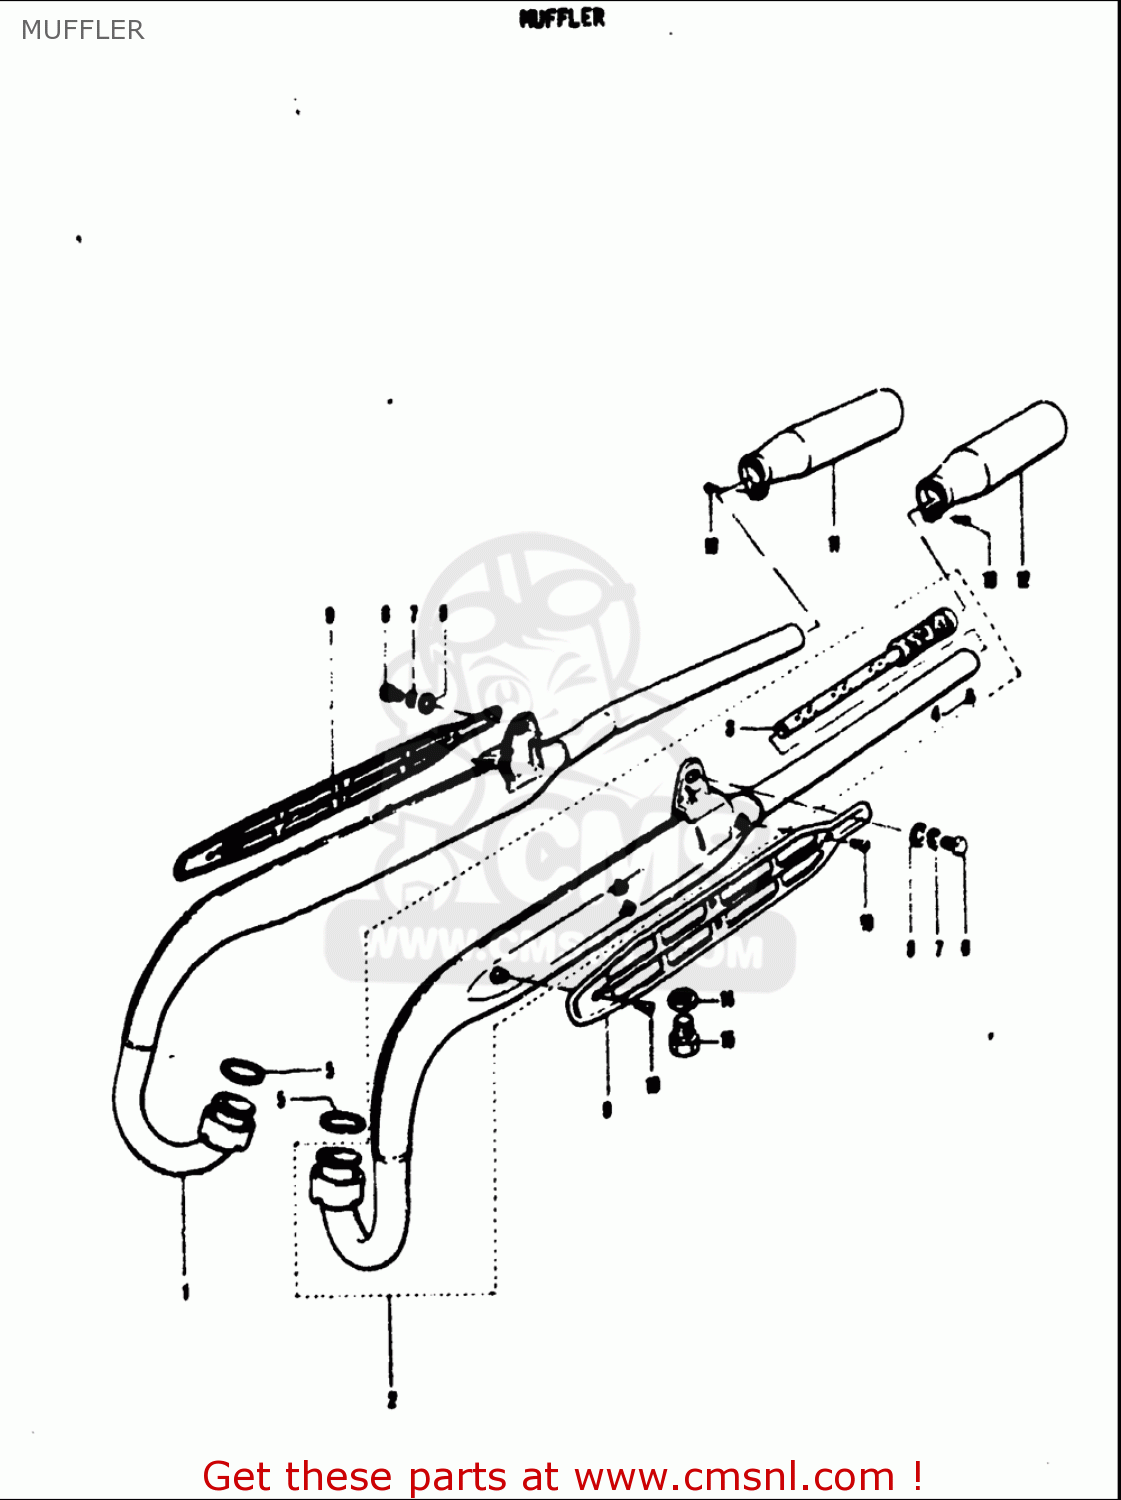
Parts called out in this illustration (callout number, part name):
4	SCREW(5X6)
5	GASKET,EXHAUST (NAS)
6	BOLT
7	WASHER,LOCK
8	WASHER
13	SCREW
14	GASKET(10X14X3.6) (NAS)
15	BOLT 10X9
